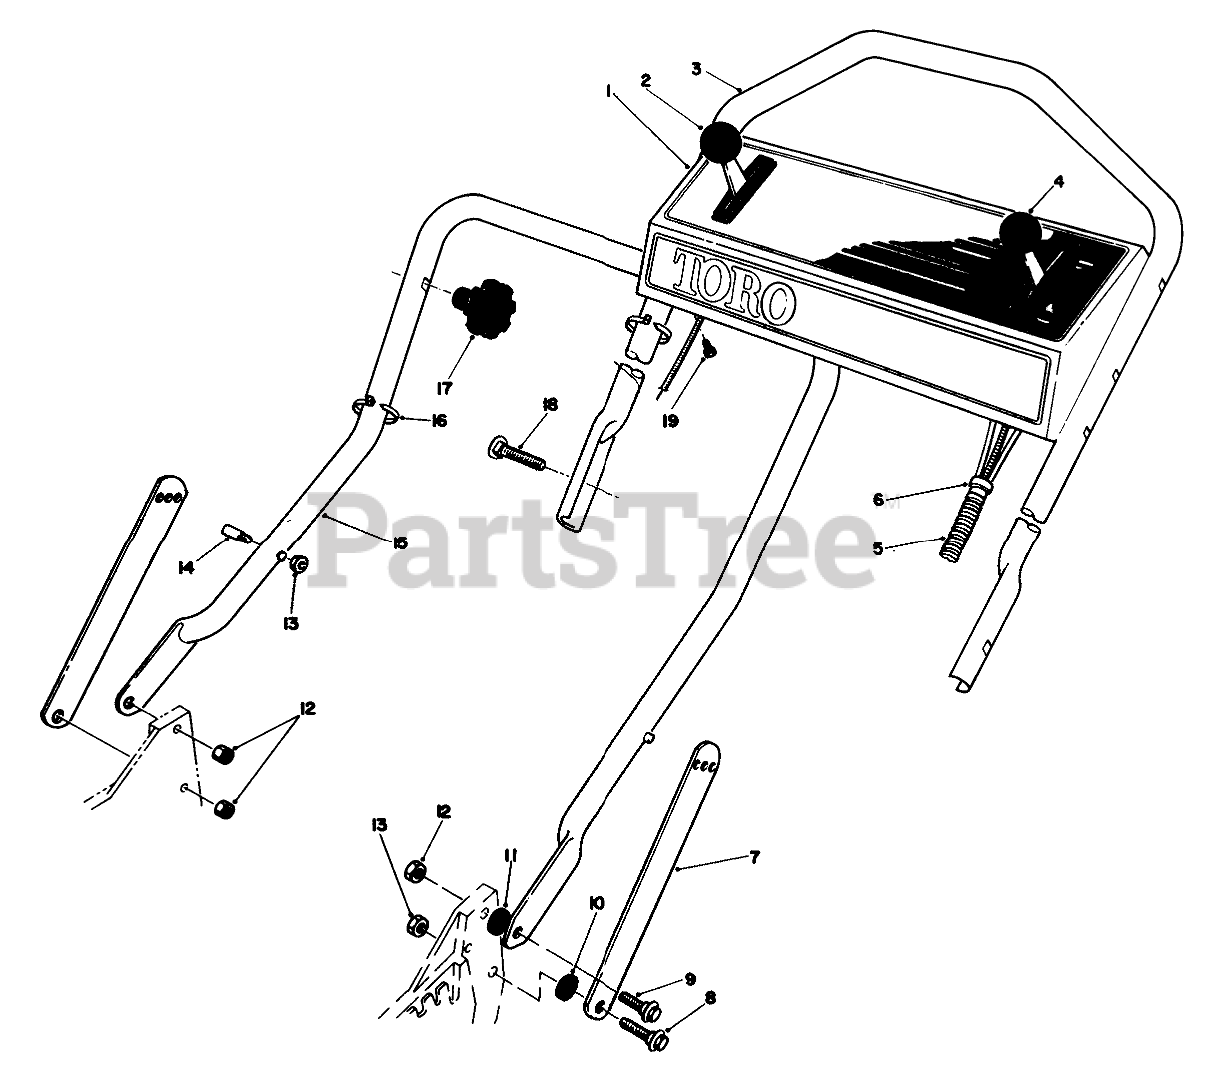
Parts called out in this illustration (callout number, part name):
1	Panel-Control
2	GROUND SPEED CONTROL
3	Handle-Upper
4	THROTTLE CONT-SERVICE
5	CONTROL CABLE COVER
6	FITTING-RING
7	Handle Latch
8	SCREW-SHOULDER
9	SCREW-SHOULDER
10	SPACER
11	SPACER
12	NUT-LOCK, NI
13	NUT-LOCK, NI
14	HANDLE PIN
15	LOWER HANDLE ASM
16	TIE-CABLE
18	5/16-18 X 2 HNDLE SCREW
19	SCREW-HWHTF
